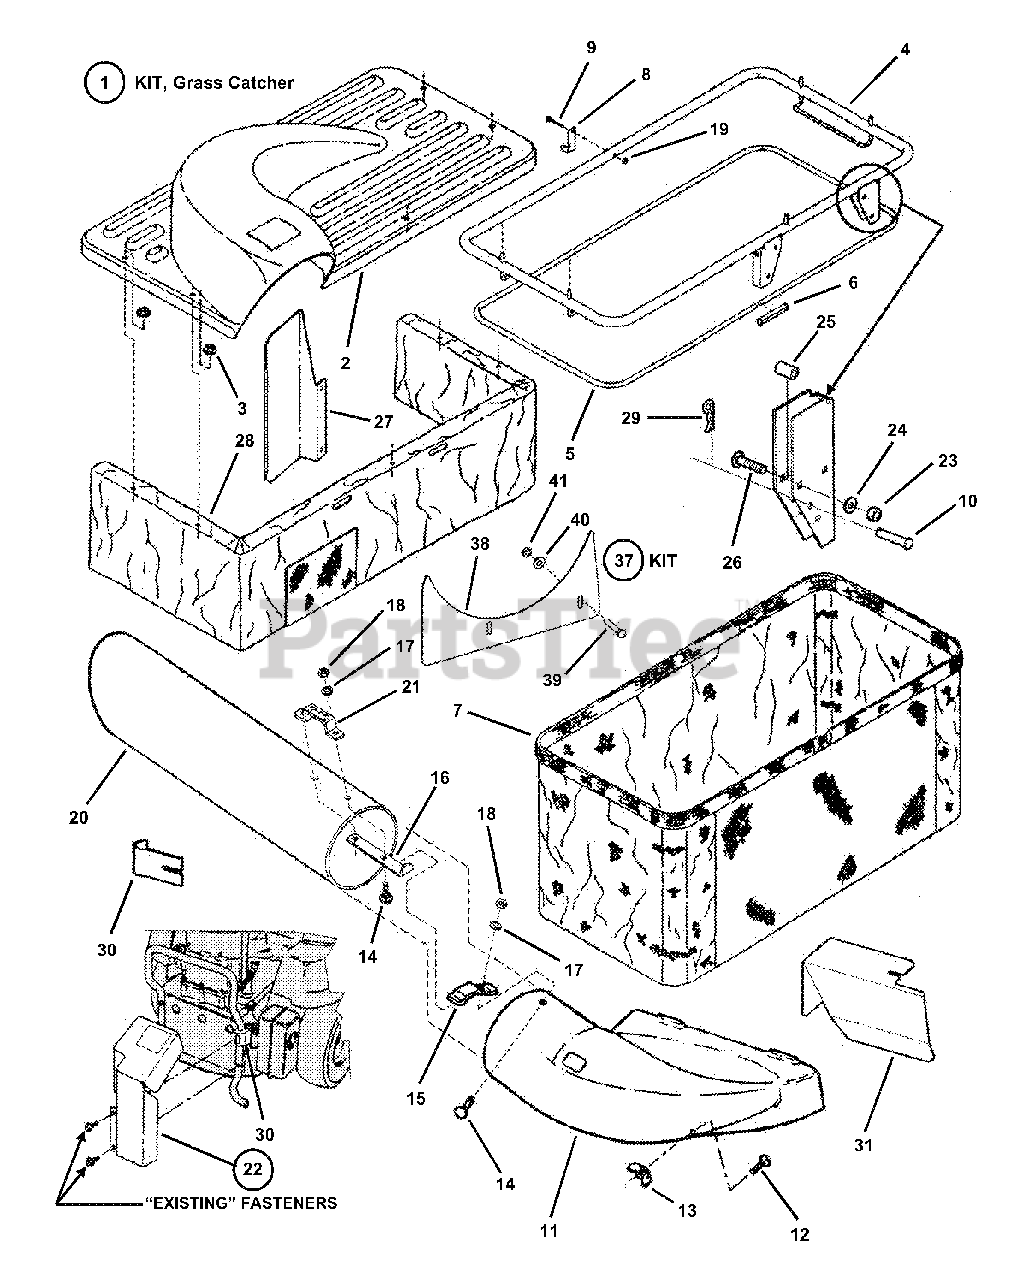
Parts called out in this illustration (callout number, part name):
1	KIT, Grass Catcher (33" Models, Series 2)
2	TOP, Container
3	WASHER, 5/16" Faceted
4	FRAME, Weldment
5	ROD, Bag
6	CONNECTOR, Bag Rod
7	BAG, Grass
8	LATCH, Top
9	SCREW, #10-32 x 1-3/8" Hex Head Machine
10	PIN, 5/16 x 1-11/16" Clevis
11	ADAPTER, Deck
12	BOLT, 5/16-18 x 1" Short Neck Carriage, Grade 5
13	WING LOCK NUT, 5/16-18
14	BOLT, 1/4-20 x 3/4" Short Neck Carriage, Grade 5
15	LATCH, Tube
16	BASE, Handle
17	WASHER, 1/4 Internal Tooth Lock
18	NUT, 1/4-20 Hex
19	NUT, #10-32 Hex Nyloc
20	TUBE, Grass (45" long)
21	HANDLE, Tube
22	ASSEMBLY, Debris Shield
23	NUT, 5/16-18 Hex Center Lock
24	WASHER, 5/16" Flat
25	PAD, Bumper Mount
26	BOLT, 5/16-18 x 1-1/2" Square Neck Carriage, Grade 5
27	SHIELD, Muffler Heat (8 HP Engines)
28	DUST SKIRT
29	PIN, 3/32 x 1-1/2" Hair
30	REINFORCEMENT, Bumper
31	HEAT SHIELD
37	KIT, Catcher Debris Shield
38	SHIELD, Debris
39	BOLT, Hex 1/4-20 x 1-1/2" Hex
40	WASHER, 1/4" Flat
41	NUT, 1/4-20 Hex Top Lock
